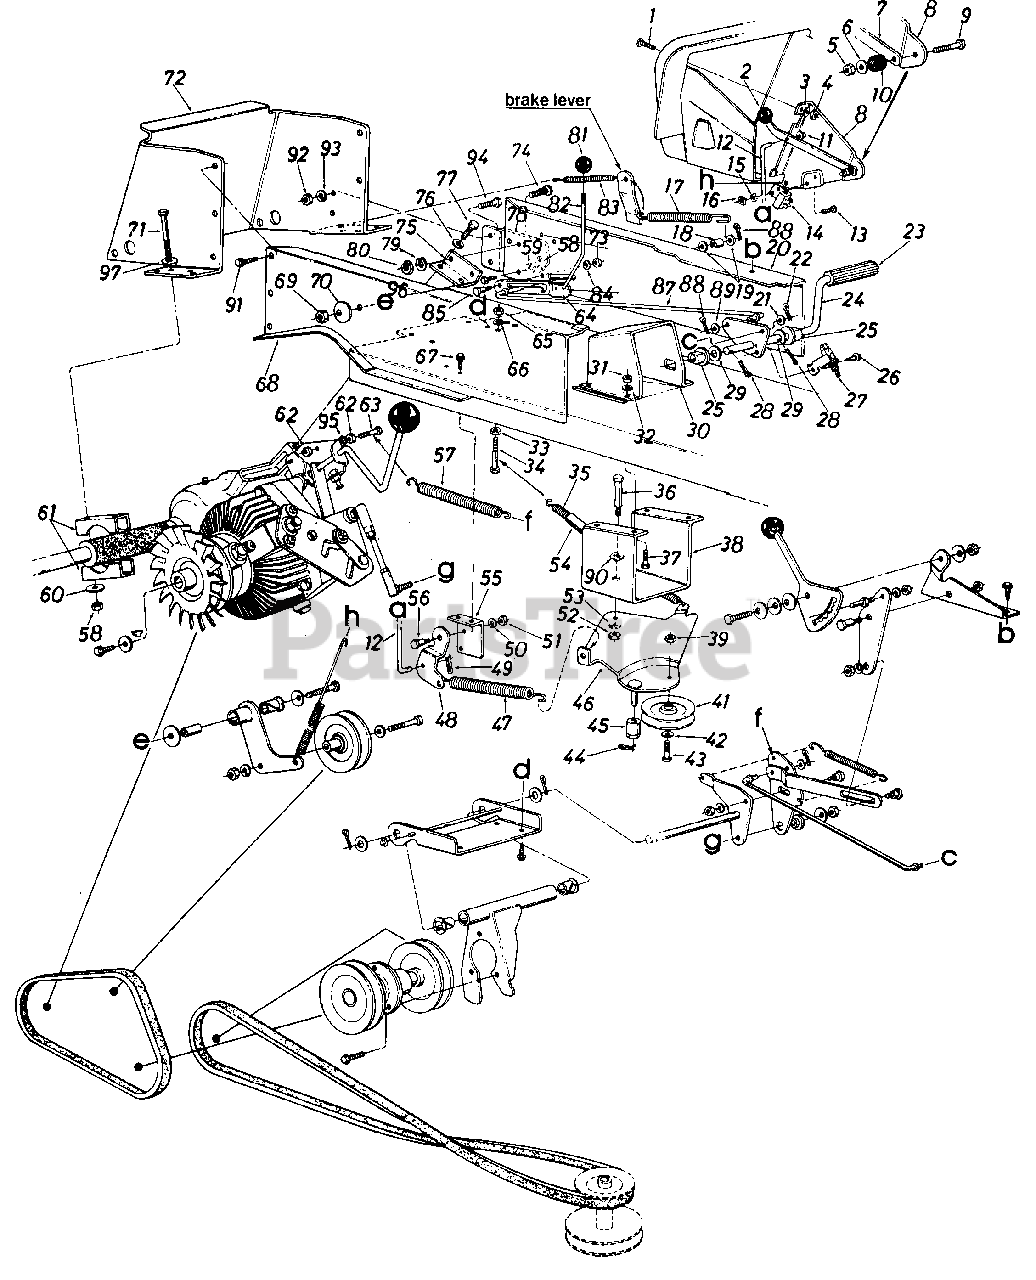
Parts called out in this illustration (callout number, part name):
1	Truss Mach. Scr. 1/4-20 x .50" Lg.
2	Knob Blade Clutch
4	Hex Sems Nut 1/4-20 Thd.
5	Hex Cent. L-Nut 1/4-20 Thd.
6	Fl-Wash. 1/4" I.D. x .75" O.D.
7	PTO Lever
8	Deck Clutch Control Brkt.
9	Hex Bolt 1/4-20 x .75" Lg.*
10	Rubber Wash. .33" I.D. x .87" O.D.
11	Push Cap 1/4" Rod
12	Deck Control Rod
13	Truss Mach. Scr. #10-24 x .50/' Lg.*
14	Safety Switch
15	Ext. L-Wash. #10 Scr.
16	Hex Nut #10-24 Thd.*
17	Extension Spring .75" O.D. x 5.56" Lg.
18	Spacer .375" I.D. x .625" O.D. x .445" Lg.
19	Fl-Wash. .385" I.D. x .87" O.D.
20	Side Panel Upper Frame L.H.
21	Fl-Wash. .385" I.D. x .87" O.D.
22	Cotter Pin 3/32" Dia. x .75"*
23	Foot Pad
24	Foot Pedal Brkt. Ass'y.
25	Flange Brg. .630" I.D. x 1.25" O.D.
26	Hex Wash. Hd. S-Tap Scr. 1/4-20 x .50" Lg.
27	Safety Switch
28	Cotter Pin 1/8" Dia. x 1.00"*
29	Fl-Wash. .640" I.D. x .24" O.D.
30	Steering Gear Support Ass'y.
31	Fl-Wash. .385" I.D. x .87" O.D.
32	L-Wash. 5116" I.D.*
33	Hex Nut 1/4-20 Thd.*
34	Hex Bolt 1/4-20 x 2.0" Lg.*
35	Extension Spring .50" O.D. x 6.37" Lg.
36	Shld. Bolt 7/16" Dia. x .16"
37	Hex Bolt 5/16-18 x 1.00"*
38	Idler Mtg. Brkt. Deck
39	Hex L-Nut 3/8-16 Thd.
41	V-ldler Pulley
42	Fl-Wash. 3/8" I.D.
43	Hex Bolt 3/8-16 x 1.75" Lg.
44	Cotter Pin 5116" Rod
45	Spacer
46	Idler Brkt. Ass'y.
47	Extension Spring Deck Control
48	Deck Control Pivot Brkt.
49	Cotter Pin 5/16" Rod
50	L-Wash. 5/16" I.D.*
51	Hex Nut 5/16-18 Thd.*
52	Hex Nut 5/16-18 Thd.*
53	L-Wash. 5/16" I.D.*
54	Convoluted Conduit .50" I.D. x 4" Lg.
55	Parking Brake Cam Mtg. Brkt.
56	Shld. Bolt 7/16" Dia. x .16"
57	Extension Spring
58	Hex Nut 3/8-16 Thd.*
59	L-Wash. 3/8" I.D.
60	Bell-Wash .39" I.D. x 1.13
61	Rear Axle Brkt.
62	Hex Nut 5/16-24 Thd.*
63	Hex Bolt 5/16-24 x 1.5"
64	Parking Brake Cam
65	Hex Nut 1/4-20 Thd.*
66	L-Wash. 1/4" I.D.*
67	Hex Wash. Hd. S-Tap Scr. 1/4-20 x .50" Lg.
68	Side Panel Upper Frame R. H.
69	Hex Nut 3/8-24 Thd.*
70	Fl-Wash. .39" I.D. x 1.5" O.D.
71	Hex Bolt 3/8-16 x 3.50" Lg.*
72	Hitch Plate
73	Hex Nut 3/8-16 Thd.*
74	Rd. Hd. Ribbed Neck Bolt 3/8-24 x 1.0" Lg.
75	Mounting Brkt. Transaxle
76	L-Wash. 3/8" I.D.*
77	Hex Bolt 3/8-16 x 1.00" Lg. (Grade 5)
78	Reinforcement Plate Frame
79	L-Wash. 3/8" I.D.*
80	Hex Nut 3/8-24 Thd.*
81	Gear Shift Knob
82	Parking Brake Link
83	Extension Spring .38" O.D. x 3.18" Lg.
84	Hex Nut 3/8-16 Thd.*
85	Shld. Bolt .500" Dia. x .170
87	Rod Brake .38" Dia. x 1 9.3" Lg.
88	Cotter Pin 3/32" Dia. x .75
89	Fl-Wash. .385" I.D. x .87"
90	Wave Wash.
91	Hex AB-Tap Scr. 5/16 x .75"
92	Hex Nut 5/16-24 Thd.*
93	L-Wash. 5/16" I.D.*
94	Hex Bolt 5/16-24 x .75" Lg.*
95	L-Wash. 5/16" I.D.*
96	Hex Bolt 3/8-16 x .75" Lg.*
97	Fl-Wash. .385" I.D. x .870" O.D.
